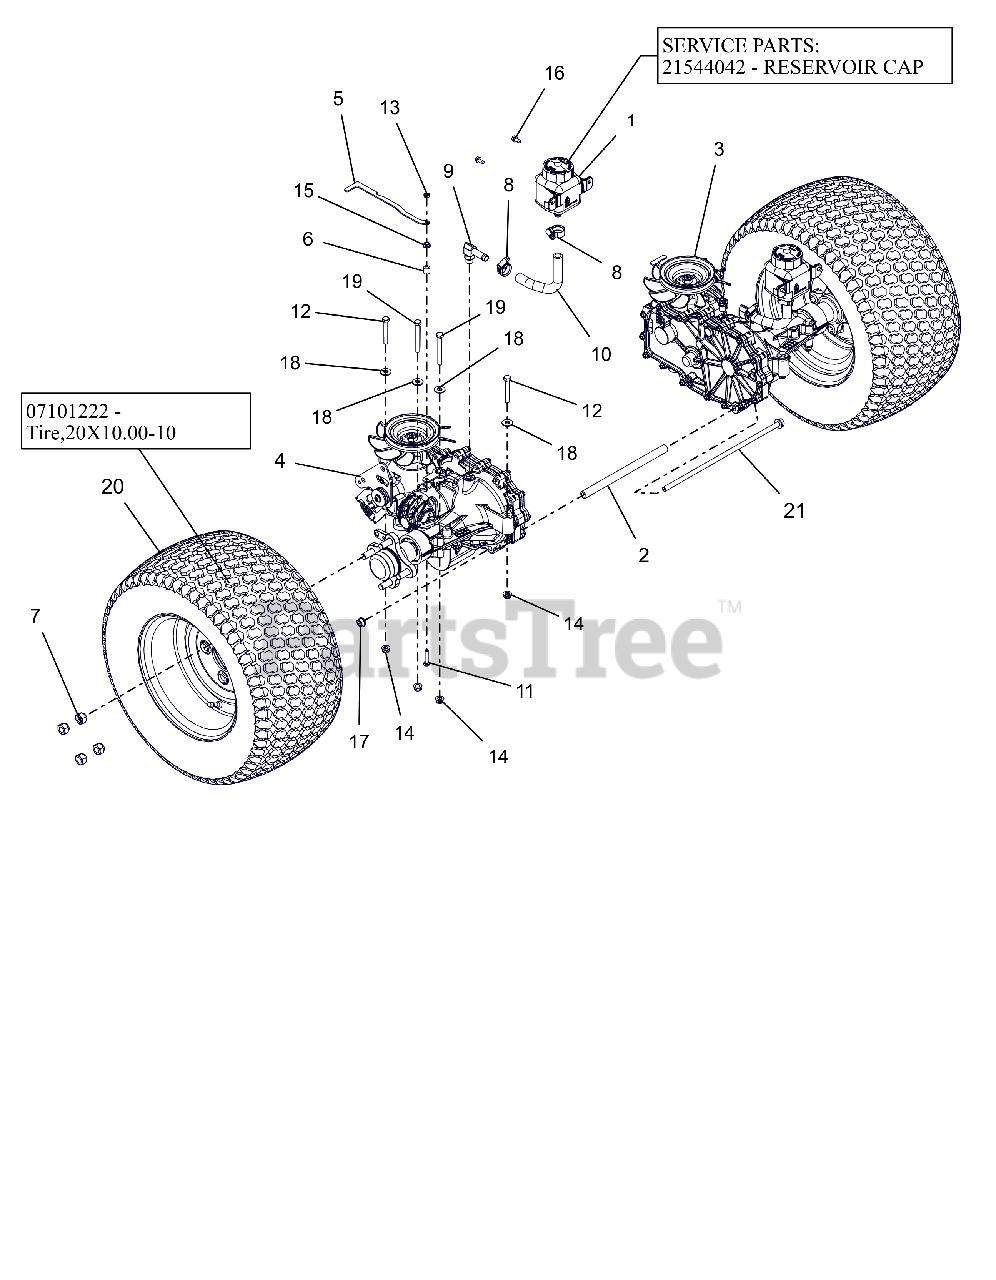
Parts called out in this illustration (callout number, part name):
1	TANK, EXPANSION
1	CAP, HYDRO RESERVOIR REPLAC.
2	TUBE, TRANSAXLE BRACE -9.27LG
3	TRANSAXLE,ZT2800 LH
4	TRANSAXLE,ZT2800 RH
5	BRKT, DUMP VALVE
6	BSHG-SLV .265X.500X.500
7	WHEEL NUT .500-20 YZ
8	CLAMP,.88 DIA. HOSE
9	FITTING, HYD (90 DEG)
10	HOSE, FORMED LH XL
11	@BLT-HEX .25-20X1.25 GR5 YWZC
12	@BLT-HEX .31-18X2.25 GR5 YWZC
13	NUT-LK-CTR JAM .25-20 YWZC
14	@NUT-LK-NYL-FLG .31-18 YWZC
15	@NUT-SPNLK-FLG .25-20 YWZC
16	SCR-TAP .25-20X.50 HWH TR YWZ
17	NUT-LK-CTR-FLG .375-16 GF ZCC
18	@WSHR-FL-STL.38X.875X.083 YWZC
19	@BLT-HEX .31-18X2.75 GR5 YWZC
20	ASM, WHL/TIRE 20X10.00-10
20	TIRE, 20X10.00-10 (OTR)
21	BLT,HEX-FLG .38-16X13 G5 ZCC
